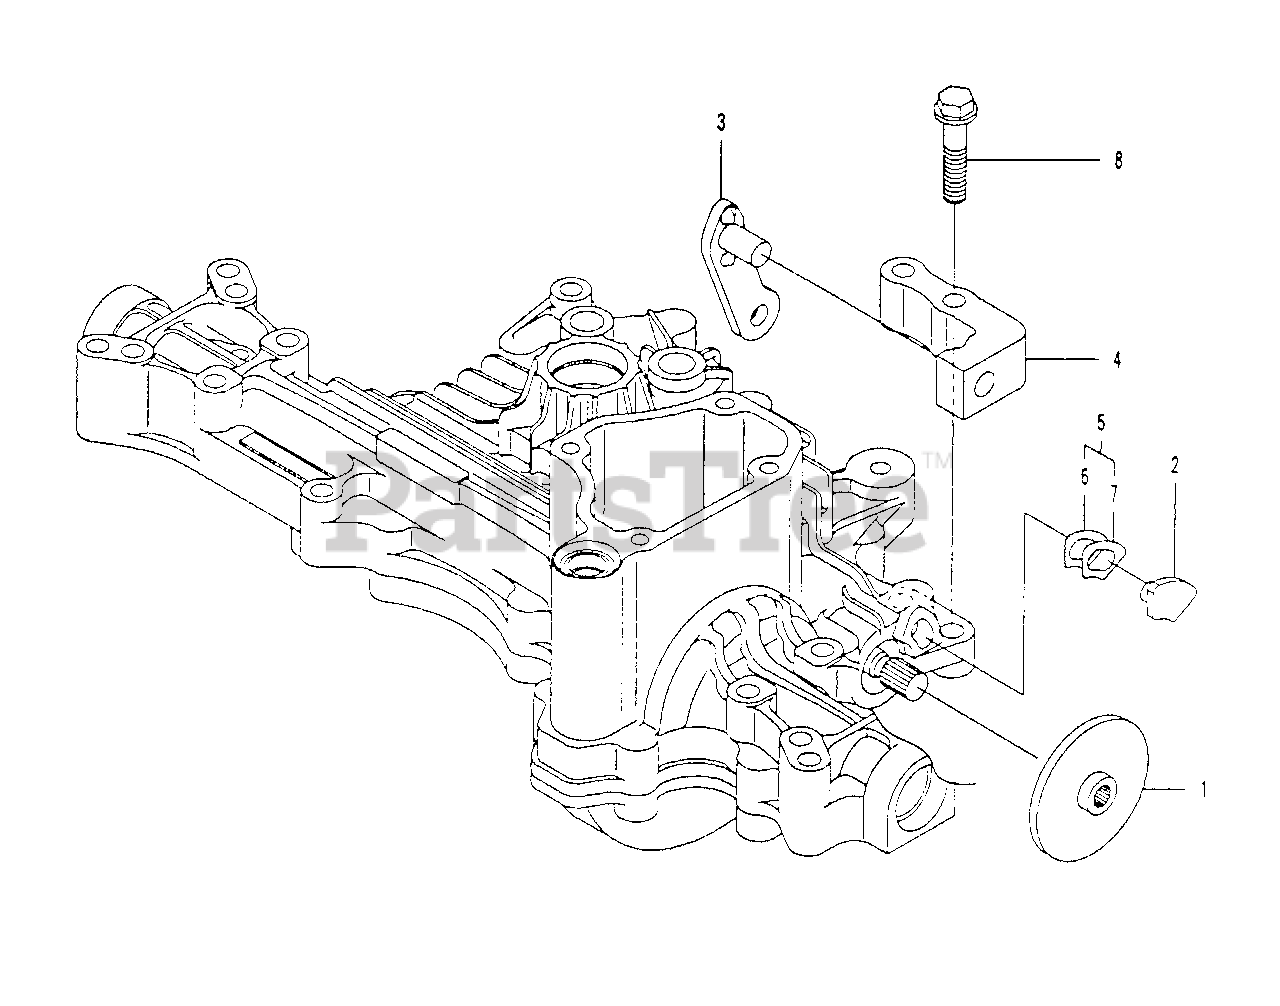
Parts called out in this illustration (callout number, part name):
1	DISK (BRAKE
2	SHOE (BRAKE
3	LEVER(BRAKE
4	STAY (BRK. LEVER
6	SHIM 0.3 (BRAKE
7	SHIM 0.5 (BRAKE
8	BOLT 10 X 45
